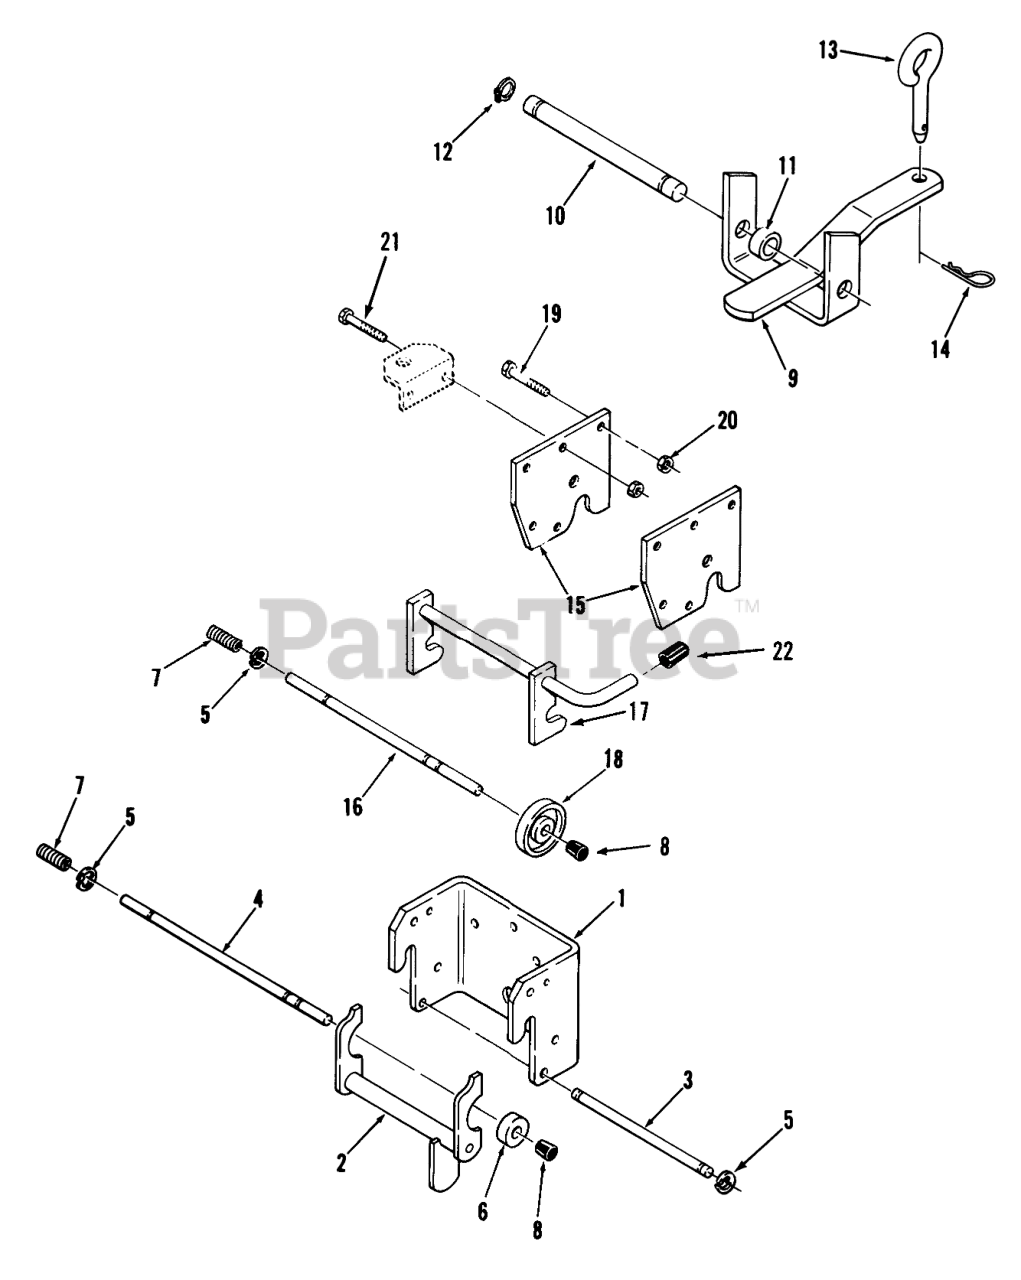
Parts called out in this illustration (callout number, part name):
3	ROD-LATCH PIVOT
4	ROD-LOCK
5	RING-RETAINING
7	SPRING
8	CAP-ROD, PLUNGER
10	PIN-STATIONARY HITCH
12	E-RING
13	PIN-TOOL
14	Hairpin Cotter
17	MID HITCH ASM
22	GRIP
